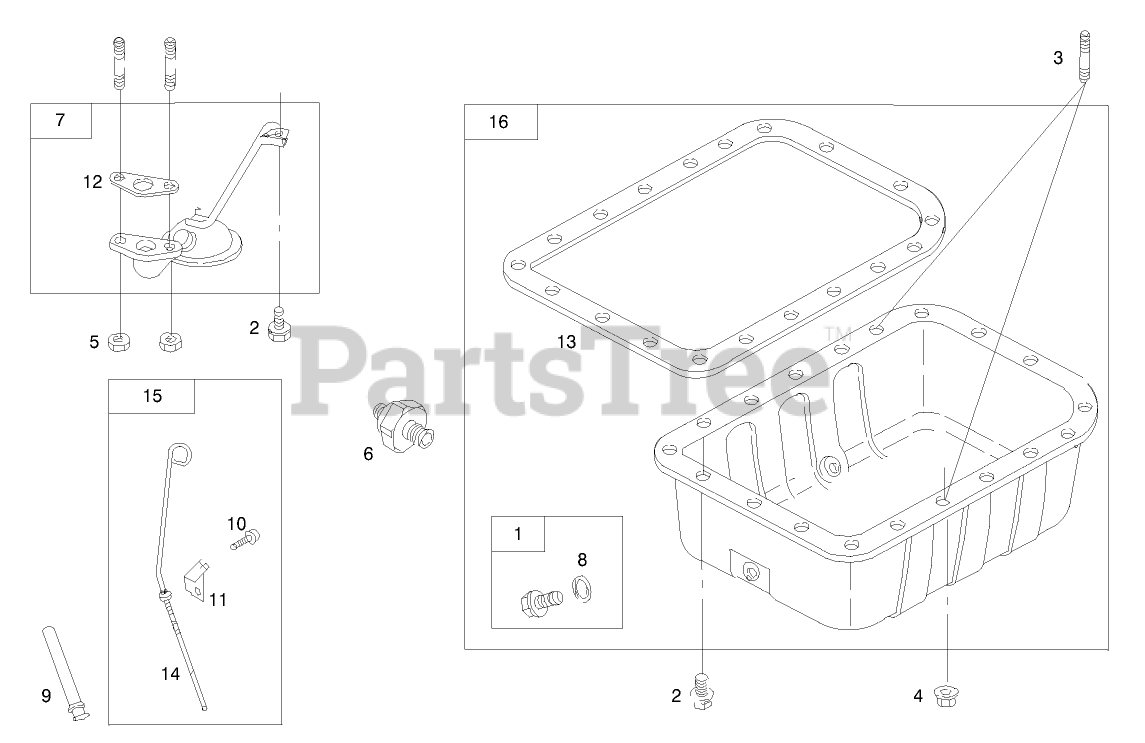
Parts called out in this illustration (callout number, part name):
1	PLUG-DRAIN, OIL
2	SCREW-HEX
3	STUD-METRIC
4	NUT-HEX, METRIC
5	NUT-HEX, METRIC
6	SWITCH-PRESSURE, OIL
7	SCREEN-PUMP, OIL
8	WASHER-SEAL
9	TUBE-DIPSTICK
10	SCREW-HEX
12	GASKET-STRAINER, OIL
13	GASKET-PAN, OIL
14	DIPSTICK
15	DIPSTICK
